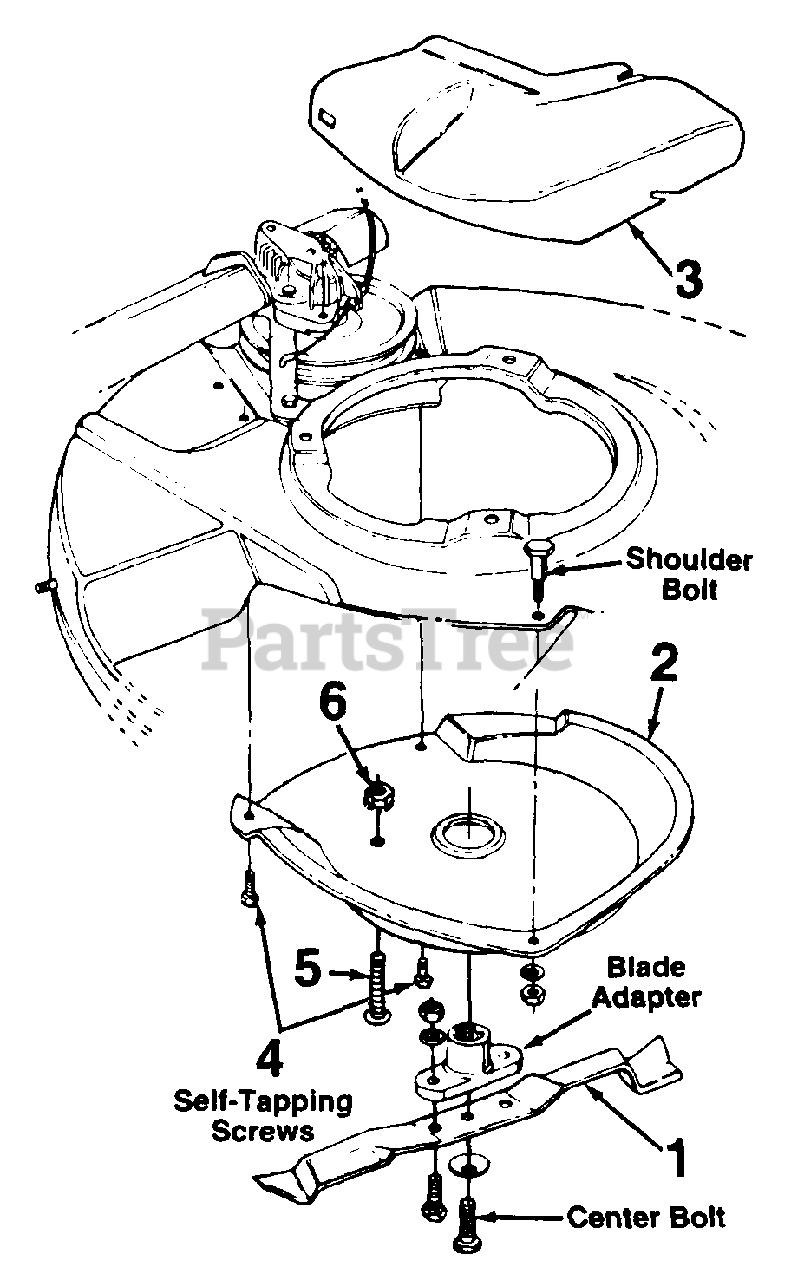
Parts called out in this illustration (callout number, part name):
1	Mulching Blade
2	Mulching Baffle
3	Mulching Plug
4	Self-Tapping Screw
5	Phillips Scr. 1/4-20 x 1.5" Lg.
6	Hex Sems Nut 1/4-20 Thd.
